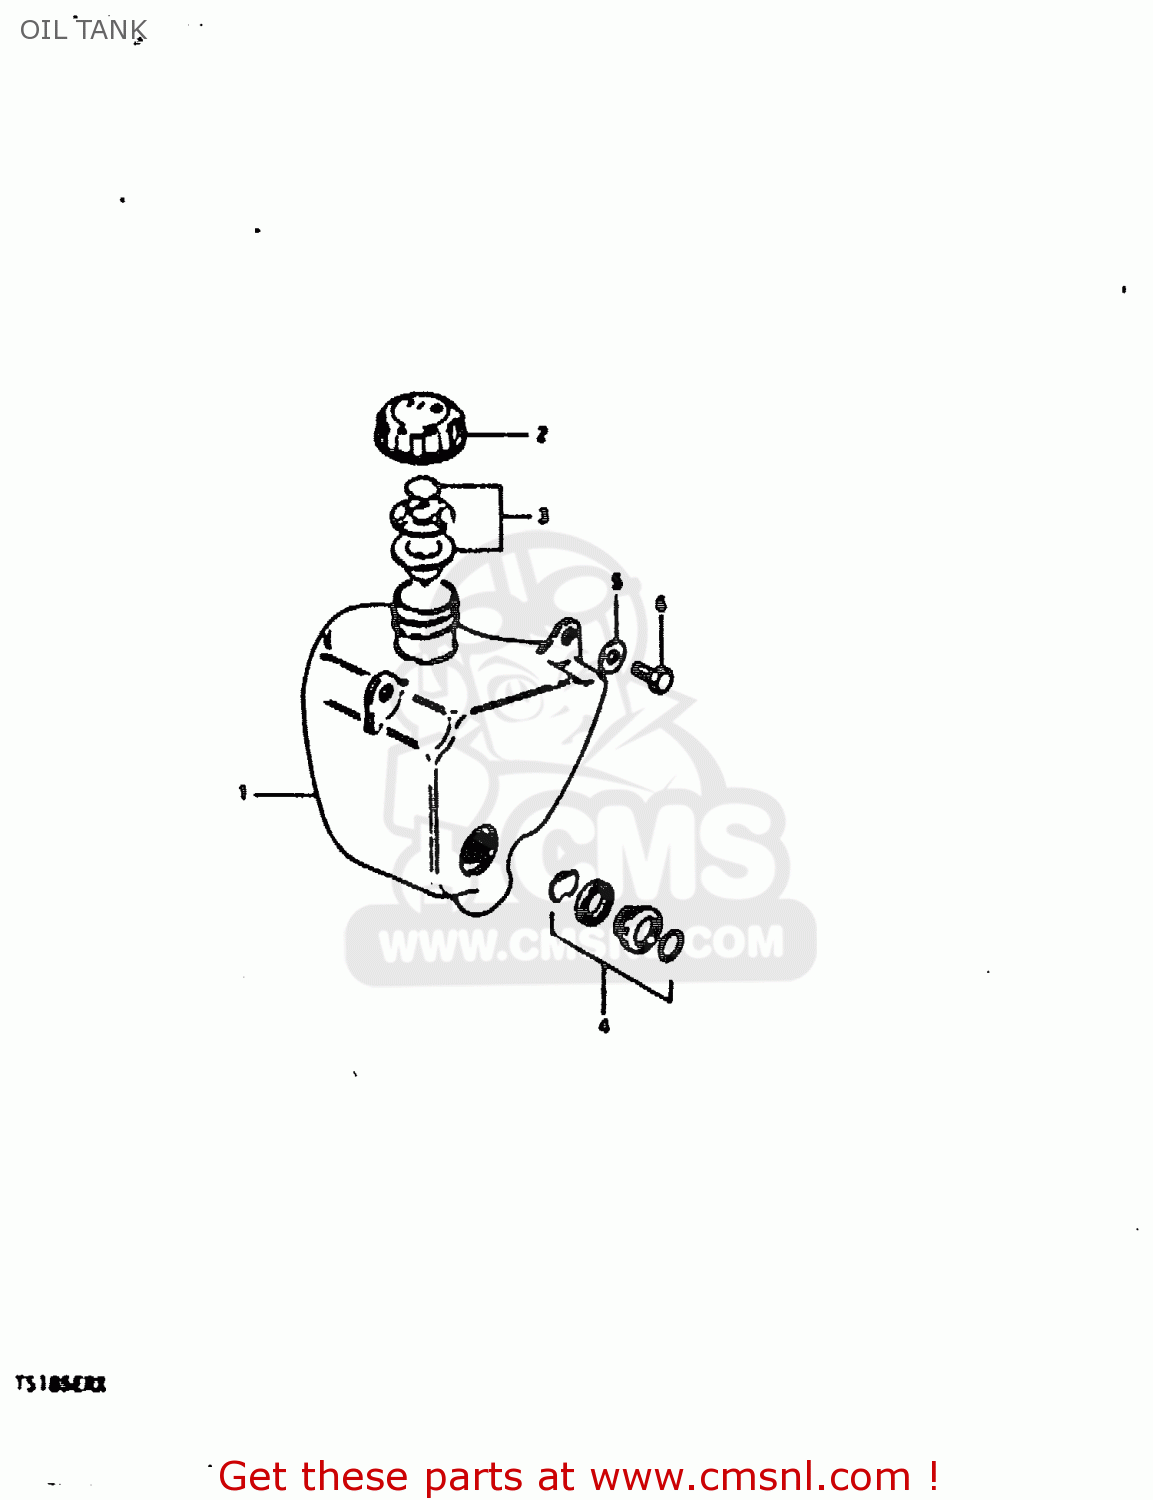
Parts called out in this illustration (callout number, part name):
1	TANK,OIL
2	CAP,OIL TANK
3	GASKET SET (NAS)
4	LENS SET,OIL LEVEL
5	WASHER
6	BOLT, UPPER
